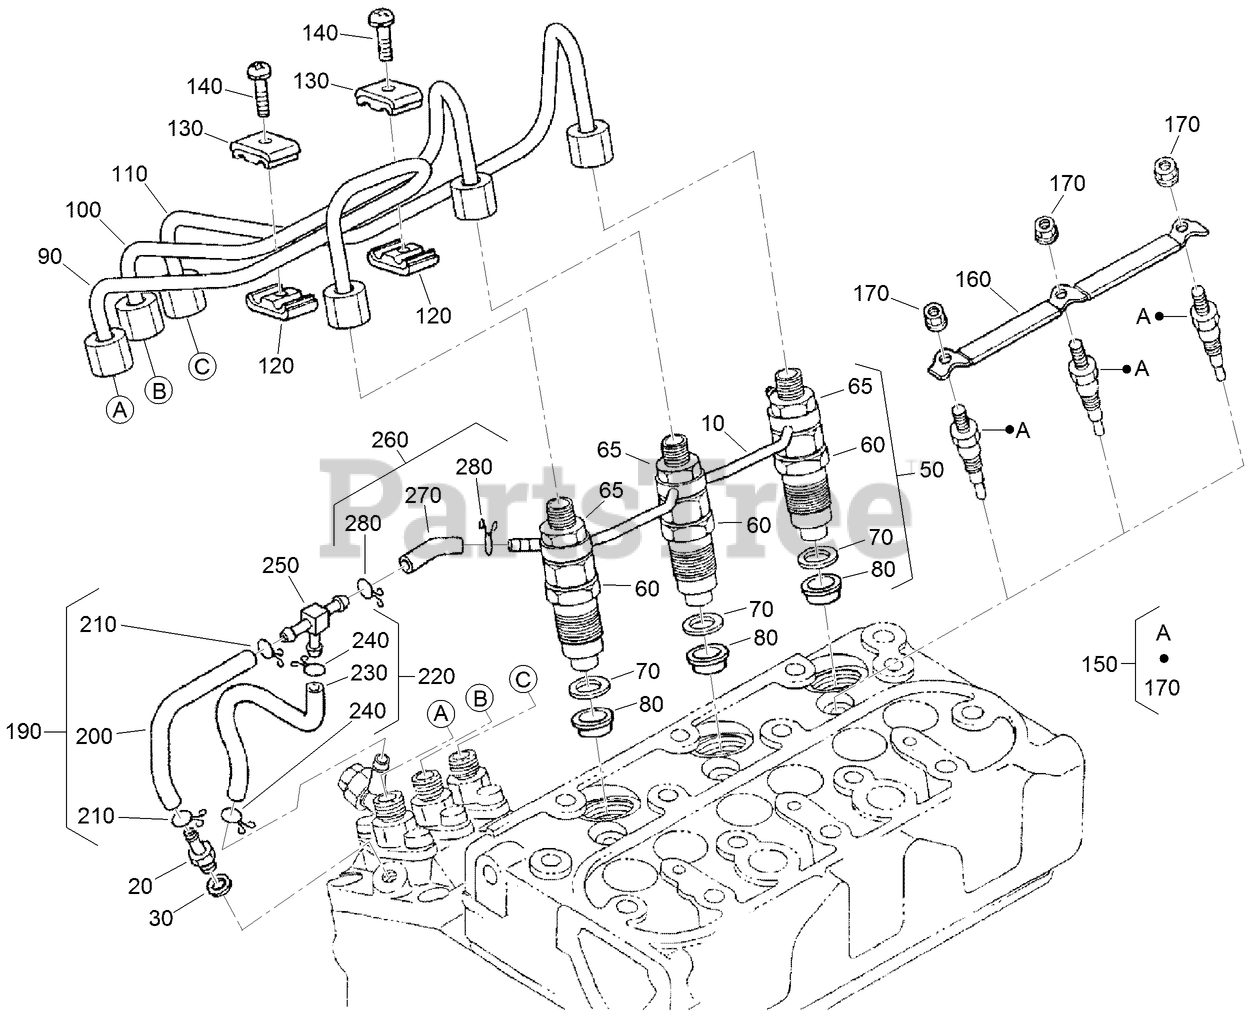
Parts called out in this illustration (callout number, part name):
10	OVER FLOW PIPE ASM
20	SCREW-BLEEDER, AIR
30	GASKET
50	NOZZLE HOLDER KIT
60	NOZZLE HOLDER ASM
70	GASKET
80	SEAL-HEAT
90	PIPE-INJECTION
100	PIPE-INJECTION
110	PIPE-INJECTION
120	CLAMP-PIPE
130	CLAMP-PIPE
140	SCREW (W/WASHER)
150	PLUG-GLOW
160	CORD-PLUG, GLOW
170	NUT-FLANGE
190	FUEL TUBE ASM
200	TUBE-FUEL
210	CLIP-PIPE
220	FUEL TUBE ASM
230	TUBE-FUEL
240	CLIP-PIPE
250	PIPE-JOINT, T
260	FUEL TUBE ASM
270	TUBE-FUEL
280	CLIP-PIPE
